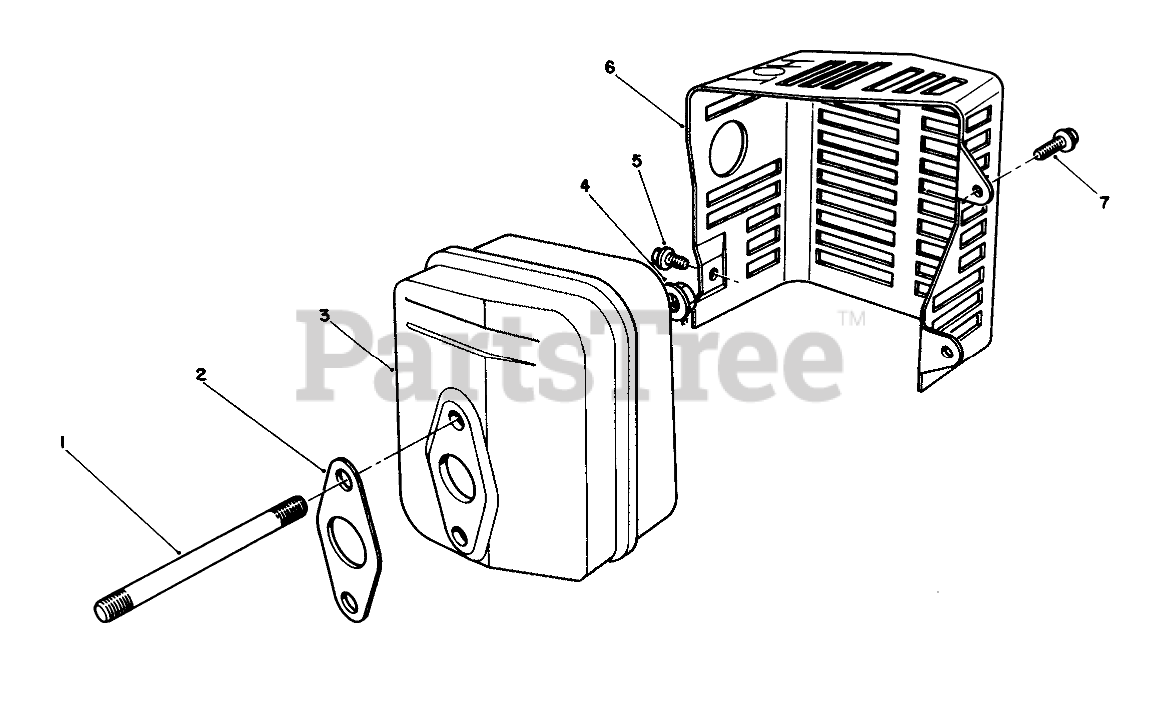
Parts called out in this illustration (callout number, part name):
2	GASKET
3	Muffler
5	Screw
6	Cover-Muffler
